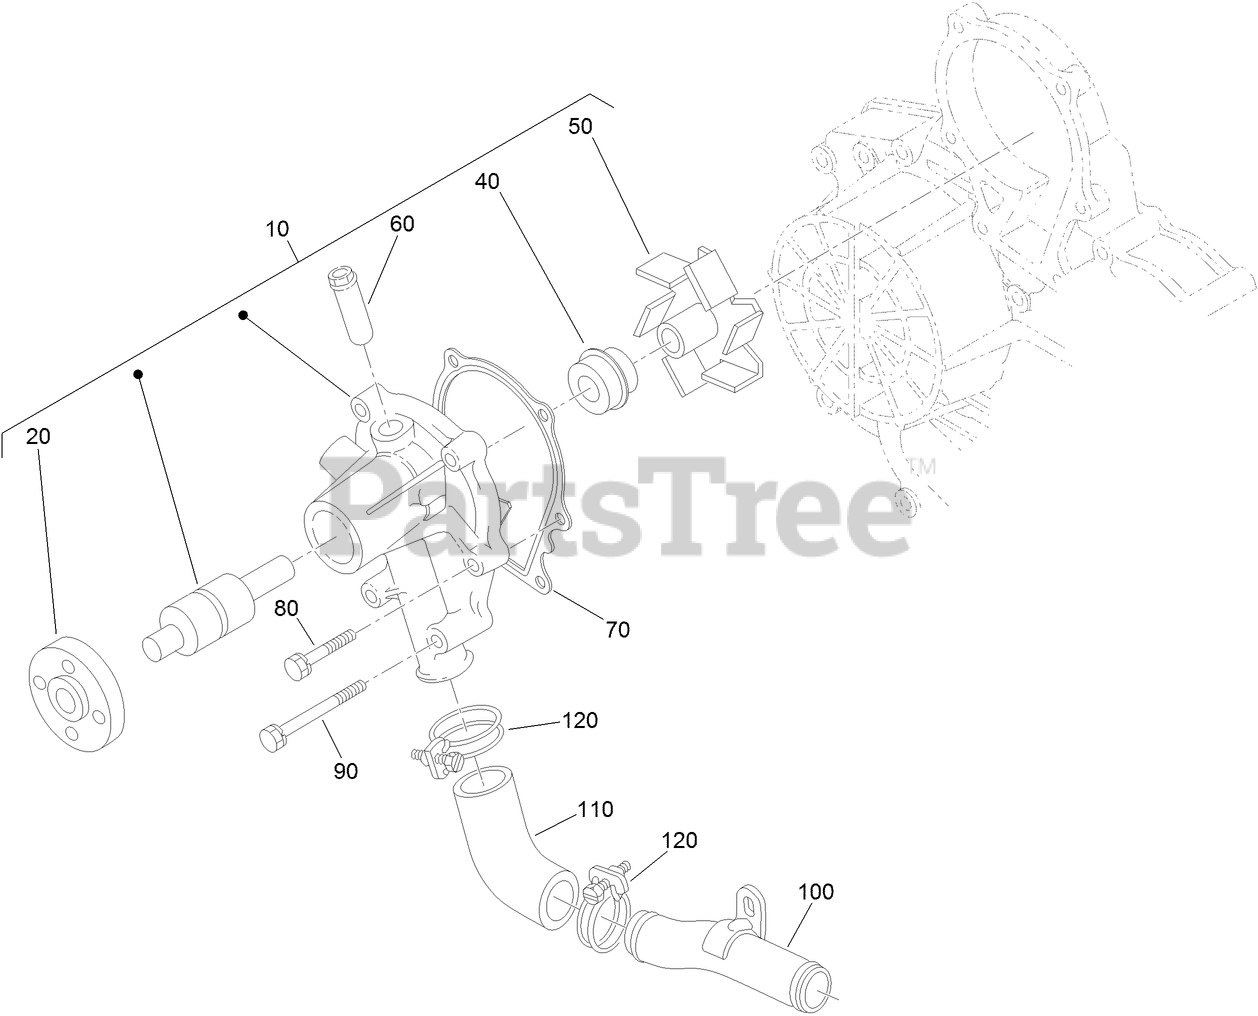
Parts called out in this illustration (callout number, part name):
10	WATER PUMP ASM
20	FLANGE-PUMP, WATER
40	MECHANICAL SEAL ASM
50	IMPELLER-PUMP, WATER
60	PIPE-RETURN, WATER
70	GASKET-PUMP, WATER
100	PIPE-WATER
110	PIPE-WATER
120	CLAMP-HOSE
